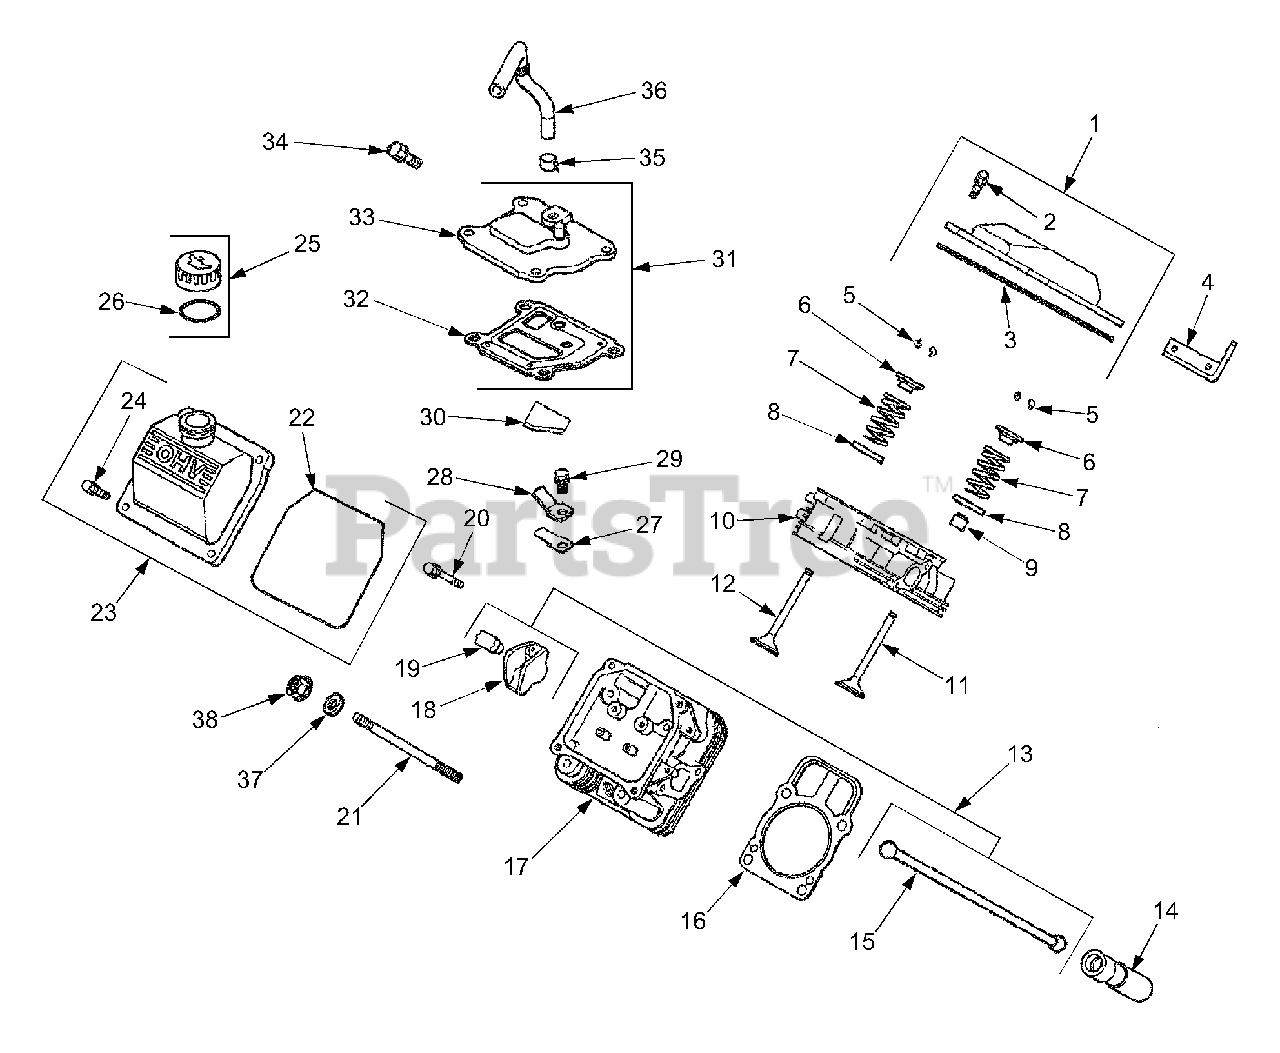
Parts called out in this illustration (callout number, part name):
1	Kit, Valve Cover
2	Screw, Shoulder
3	O-Ring, Valve Cover
4	Strap, Lifting
5	Kit, Retainer
6	Cap, Valve Spring
7	Spring, Valve
8	Retainer, Spring
9	Seal, Valve Stem
10	Head Assembly, #1 Cylinder
11	Valve, Intake (Std.)
12	Valve, Exhaust (Std.)
13	Kit, Valve Train
14	Lifter, Valve
16	Gasket, Cylinder Head
17	Head Assembly, #2 Cylinder
19	Pivot, Rocker Arm
20	Screw, Hex Flange M6 x 1 x 34
21	Stud, Cyl. Hd.
22	O-Ring, Valve Cover
23	Cover, Valve - Oil Fill
24	Screw, Shoulder
25	Cap Assembly, Oil Fill
27	Reed, Breather
28	Retainer, Breather Reed
29	Screw, Hex Flange M5 x 0.8 x 10
30	Filter, Breather
31	Kit, Breather
32	Gasket, Breather
33	Cover, Breather
34	Screw, Hex Flange M6 x 1.0 x 20
35	Clamp, Breather
36	Hose, Breather
37	Washer, Flat, 8mm
38	Nut, Hex Flange, M8 x 1.25
